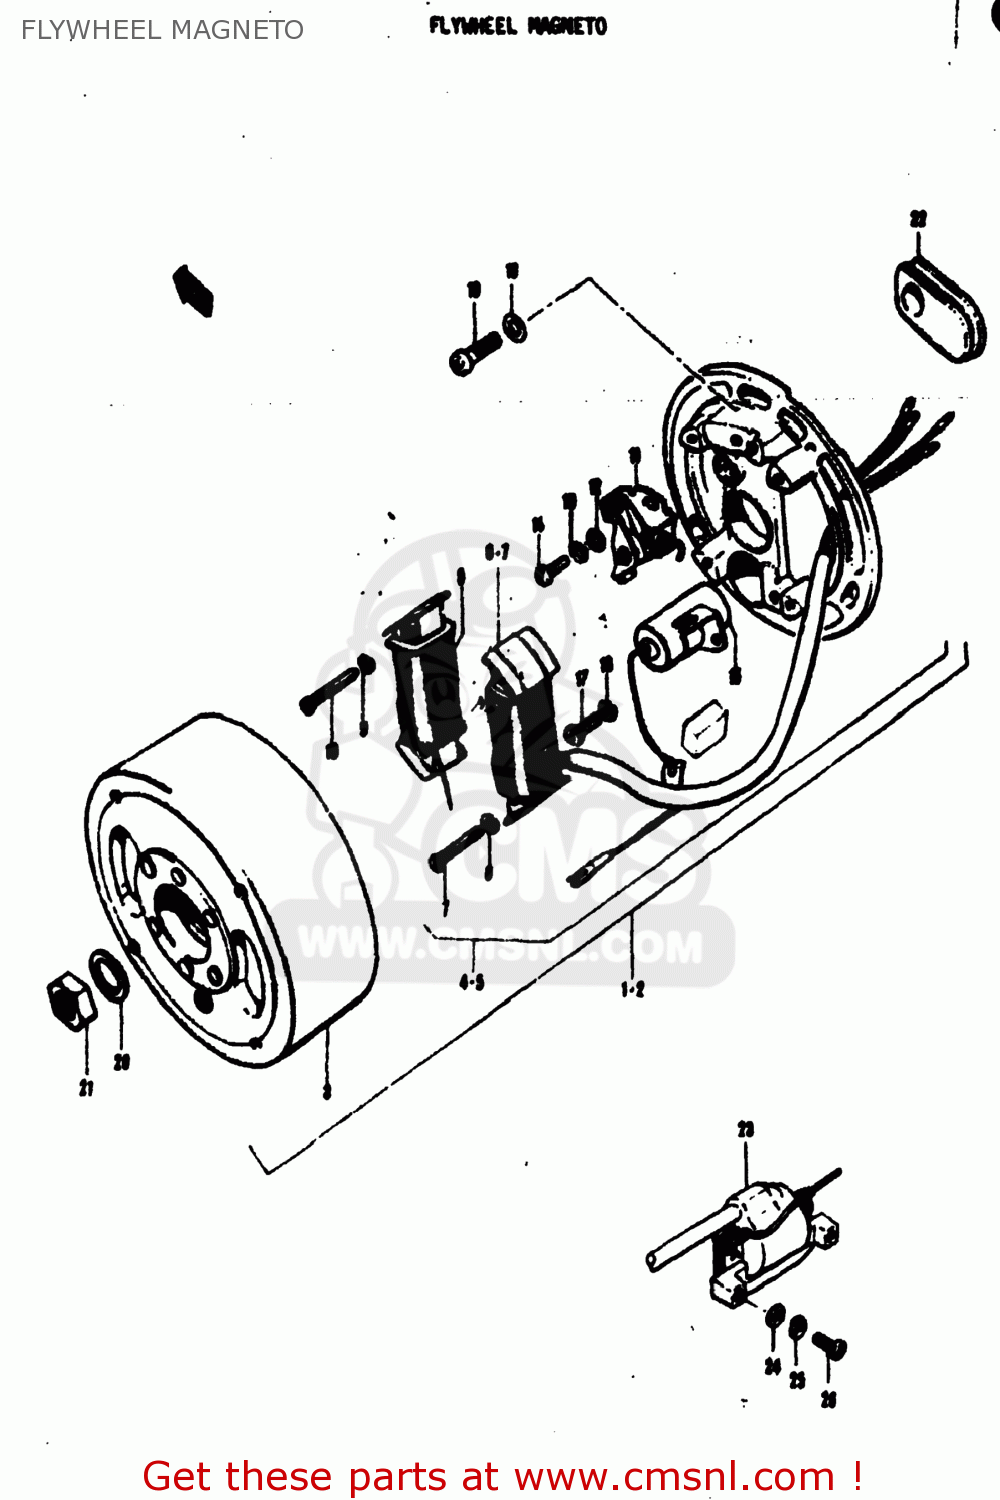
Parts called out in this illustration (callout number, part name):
1	MAGNETO ASSEMBLY
2	MAGNETO ASSEMBLY
3	ROTOR ASSEMBLY
4	STATOR ASSEMBLY
5	STATOR ASSEMBLY
6	COIL,LIGHTING
7	COIL,LIGHTING
8	COIL
9	LOCK WASHER
10	SCREW
11	POINT ASSEMBLY,CONTACT
12	WASHER
13	LOCK WASHER
14	.SCREW
15	CONDENSER
16	LOCK WASHER
17	.SCREW
18	WASHER
19	SCREW
20	LOCK WASHER
21	NUT
22	GROMMET
23	COIL ASSEMBLY,IGNITION
24	WASHER
25	LOCK WASHER
26	Screw
